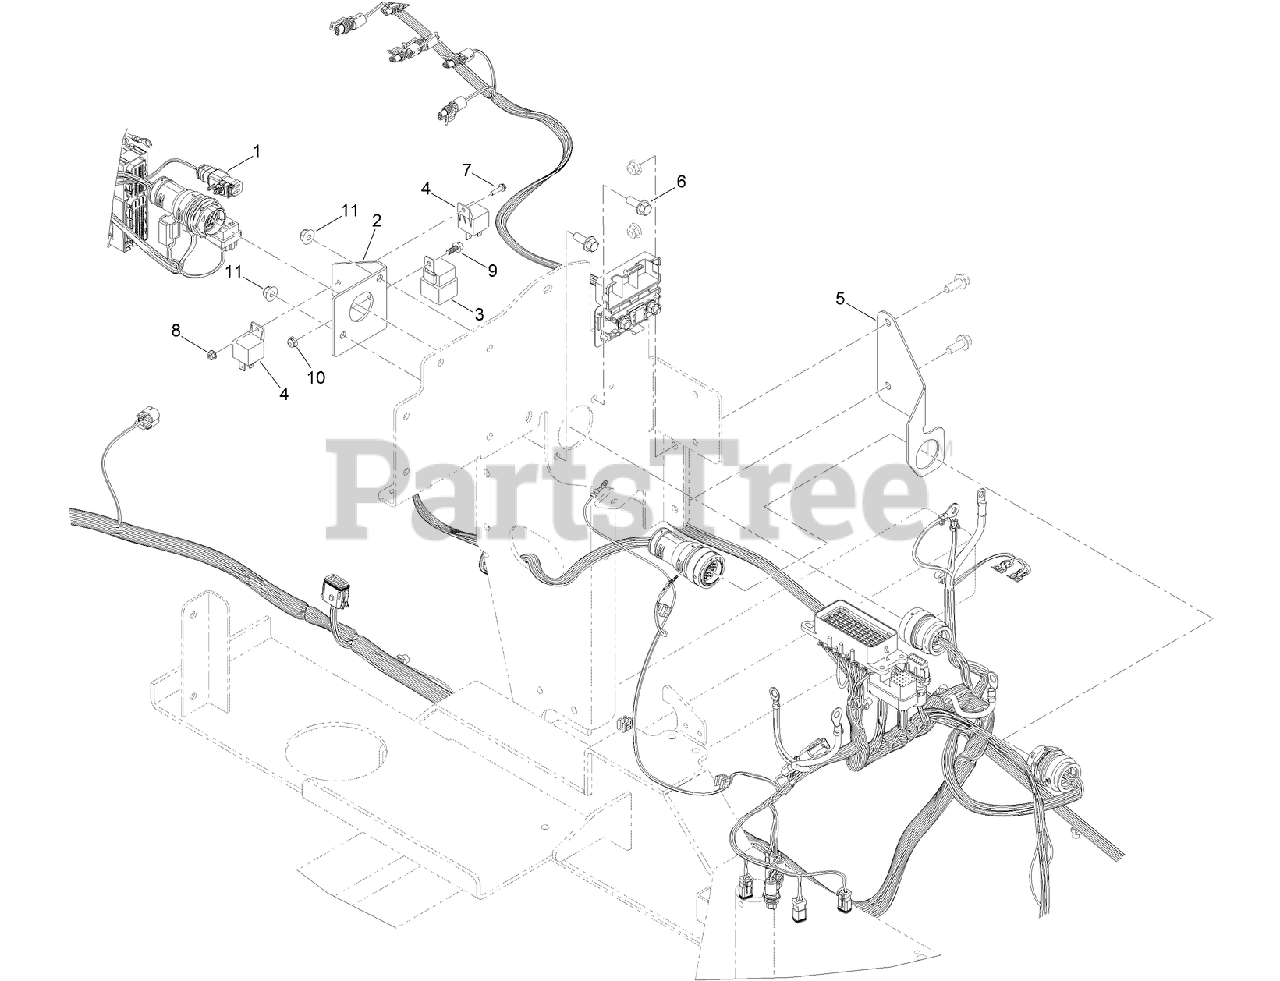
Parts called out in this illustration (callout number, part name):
1	HARNESS-WIRE
2	BRACKET-CONNECTOR
3	RELAY-MINI
4	RELAY
5	BRACKET-ELECTRICAL
6	SCREW-HHF
7	SCREW-HWH
8	NUT-HF
9	SCREW-HHF
10	NUT-HF
11	NUT-HF, NI
